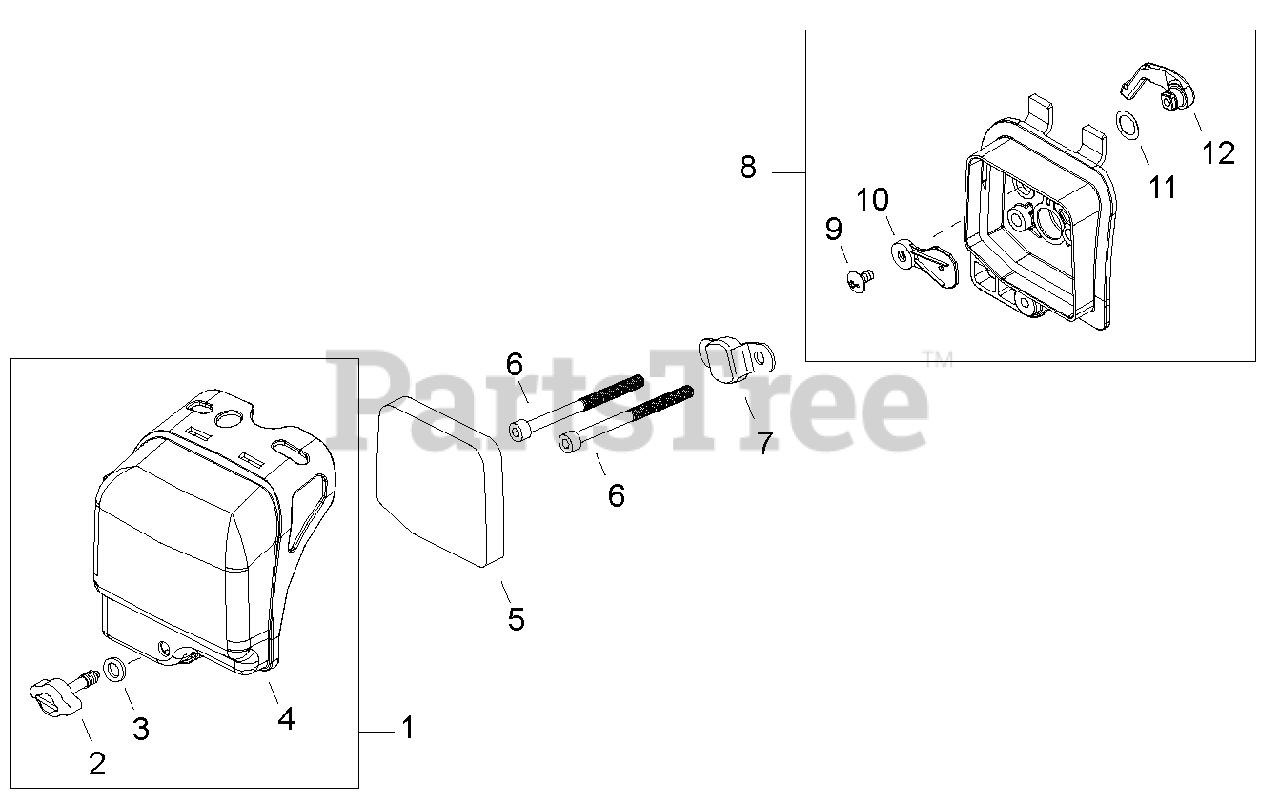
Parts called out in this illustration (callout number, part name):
2	THUMBSCREW
3	WASHER 5
4	COVER, AIR FILTER
5	FILTER, AIR
6	BOLT M5×60
7	BRACKET
8	CASE ASSY, AIR FILTER
8-1	COVER ASSY, AIR FILTER
9	SCREW, TRUSS M4×12
10	PLATE, CHOKE
11	WASHER, WAVE
12	LEVER, CHOKE
